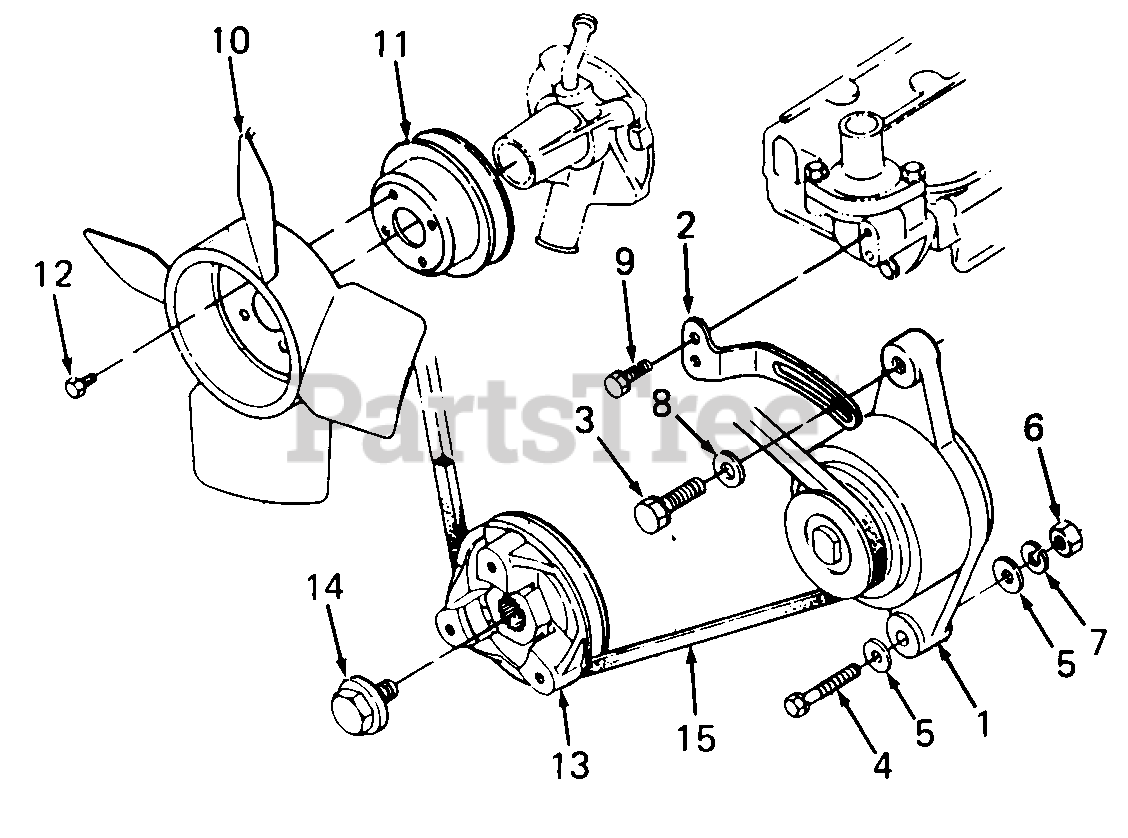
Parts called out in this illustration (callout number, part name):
1	Alternator Assy
2	Stay, Alternator
5	Washer, Plain
7	Washer, Spring
8	Washer, Plain
13	Pulley, Fan Drive
